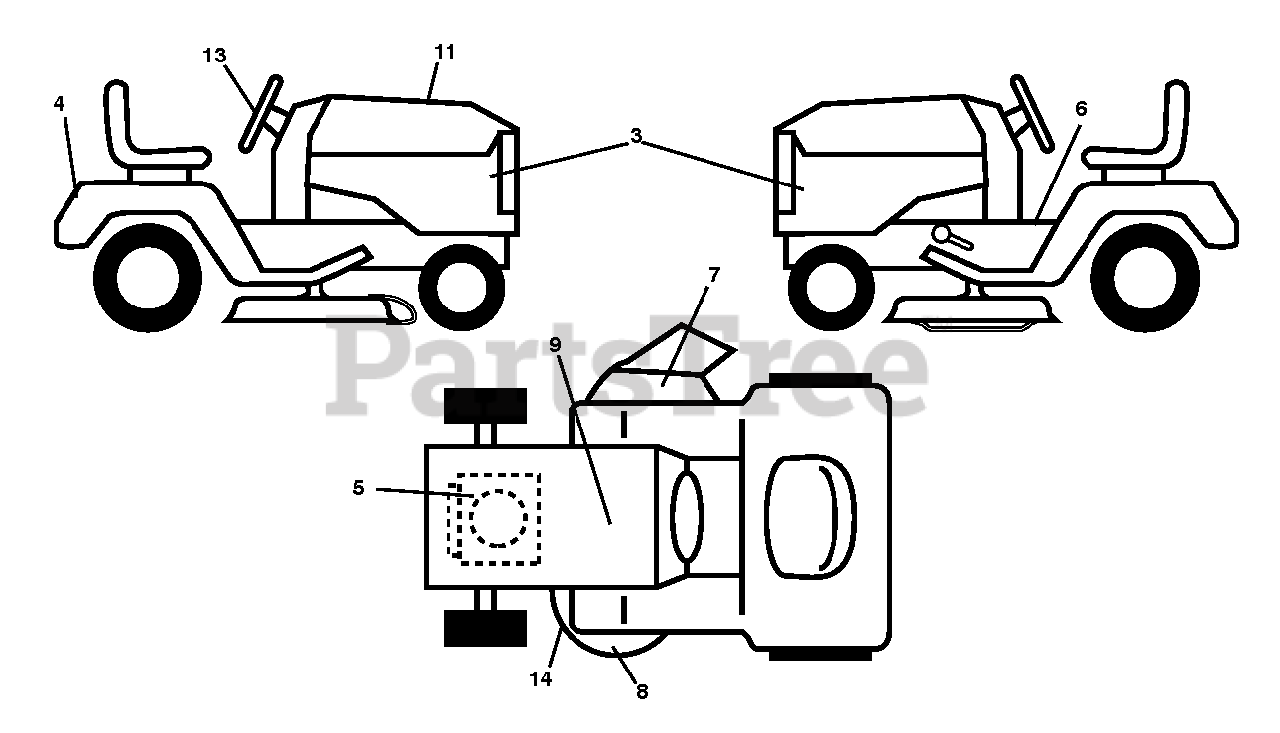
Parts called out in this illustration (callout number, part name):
3	DECAL TRACTOR SIDE PANEL DECAL
4	DECAL.REARFNDR.POULAN PRO.2015
5	Decal, Engine BS 20INTK DOM 381707
6	DECAL.FENDER.WARNING.ENGLISH
7	DECAL, DECK DEFLECTOR, WARNING
8	DECAL.PPRO.10YRDECKWAR.POP
9	DECAL BTRY SYMBOLS
11	Decal, Replacement BSM40 TLW 46 GENTRL
13	DECAL.STRWHL.BLK.2014.PPRO
14	DECAL.V-BELT.SCH.42/46"MEC/ELE
